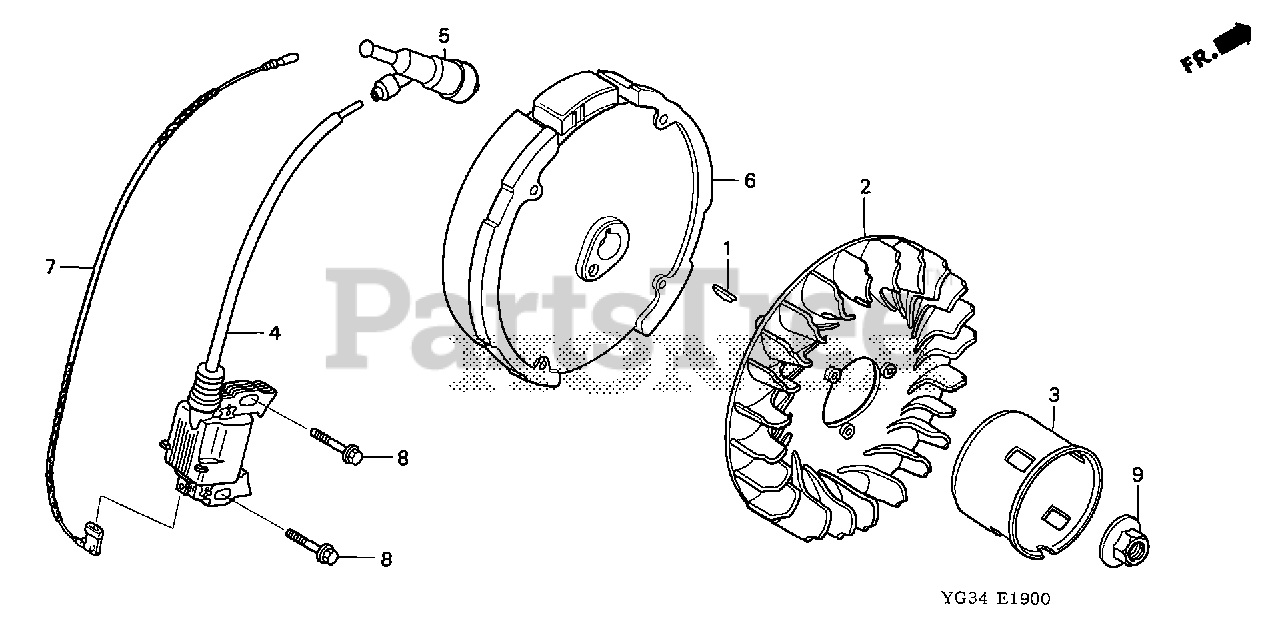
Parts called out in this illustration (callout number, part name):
1	KEY, SPECIAL WOODRUFF (25X18)
2	FAN, COOLING
3	PULLEY, STARTER
4	COIL ASSY., IGNITION (TEC)
5	CAP ASSY., NOISE SUPPRESSOR (NGK)
5	CAP ASSY., NOISE SUPPRESSOR (TEC)
7	WIRE, STOP SWITCH (370MM)
8	BOLT, FLANGE (6X25) (CT200)
9	NUT, SPECIAL (14MM)
